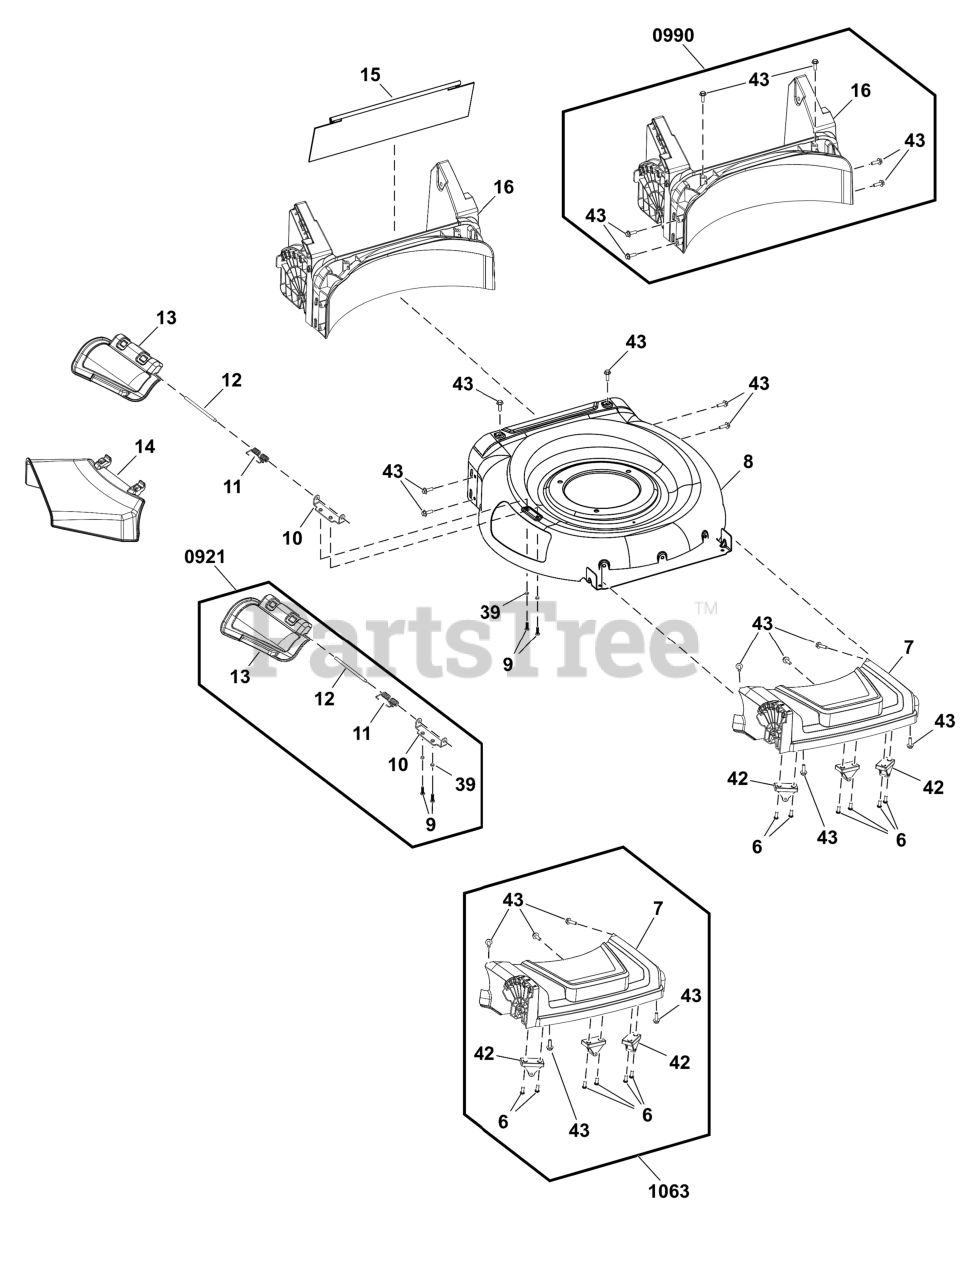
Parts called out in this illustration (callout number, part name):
6	SCREW
7	HOUSING, Front
8	DECK
9	SCREW
10	BRACKET, Deflector
11	SPRING, Deflector
12	SHAFT, Deflector
13	COVER, Mulch
14	DEFLECTOR
15	COVER, Dust
16	HOUSING, Rear
39	WASHER
42	BASE, Stabilizer
43	SCREW, Hex Head
0921	KIT, Mulching
0990	KIT, Housing, Rear
1063	KIT, Housing, Front
